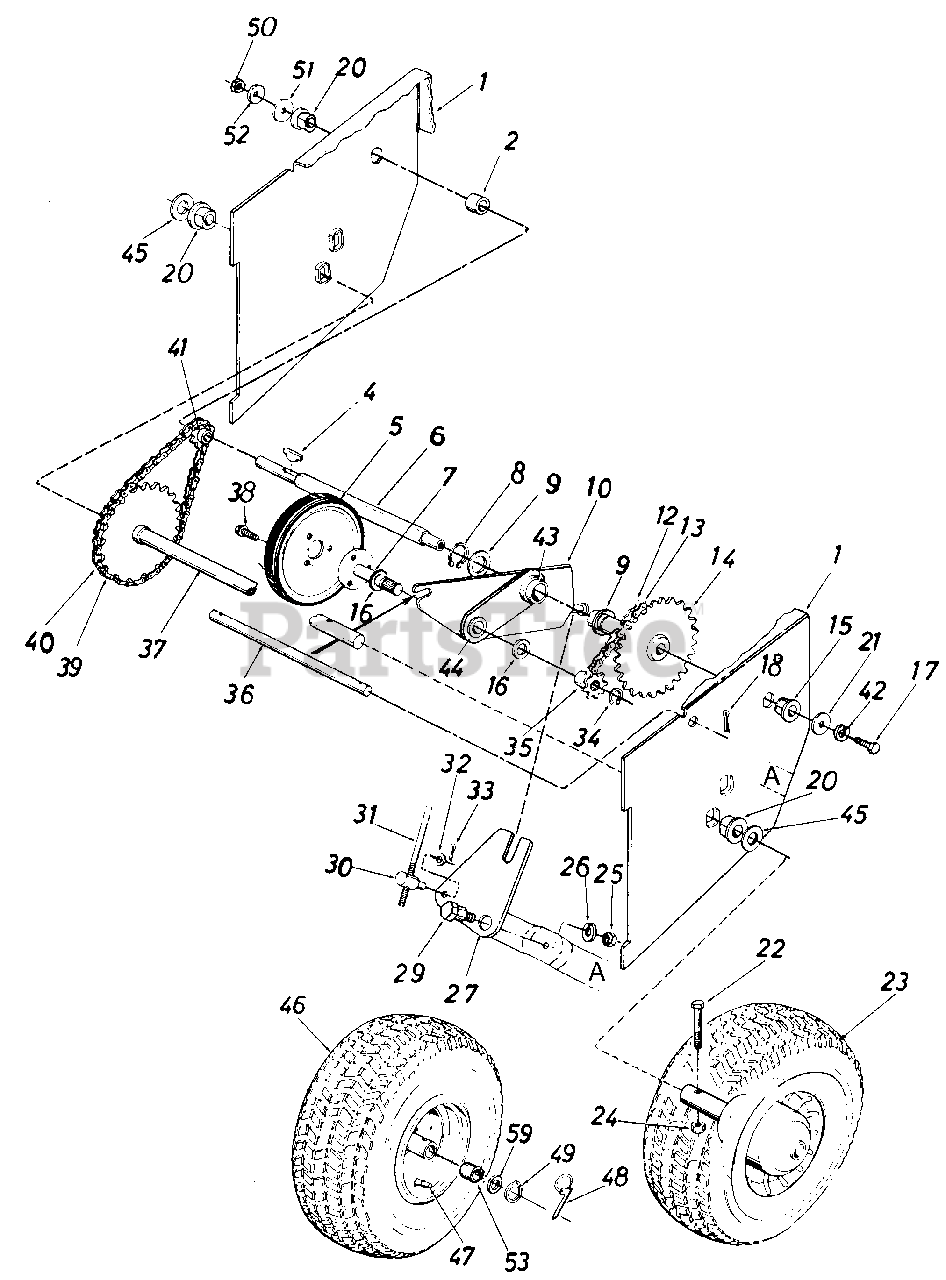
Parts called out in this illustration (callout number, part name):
1	FRAME ASSY
4	KEY-HI-PRO #4-3/32X5/8 DIA-HDN
5	WHEEL ASSY-FRICTION
6	SHAFT-HEX
7	PLATE ASSY-FRICTION WHEEL MTG
8	RING-SNAP FOR 1.00 DIA SHAFT
9	WASHER-FL-1.03 ID X 1.62 X .03 HD
10	BRACKET ASSY-SLIDING
12	#41 CHAIN 1/2" PITCH X 35 LINKS
13	#41 MASTER LINK 1/2 PITCH TYPEII
14	SPROCKET ASSY-32T
15	BEARING-FLANGE
16	WASHER-FL
17	SCREW-HEX 5/16-18 X .62
18	PIN-COTTER-3/32 DIA X .75
20	BEARING-FLANGE W/FLATS
21	WASHER-FL-.312 X 1.125 X .125
22	SCREW-5/16-24 X 1.5
24	NUT-HEX INS JAM LOCK 5/16-24
25	NUT-HEX JAM 3/8-18
26	WASHER-LOCK-3/8
27	BRACKET-LINKAGE
29	SCREW-SHLD .625 DIA X .163
30	FERRULE-ADJ
31	ROD-SHIFT
32	WASHER-FL-.344 X .62
33	PIN-COTTER-3/32 DIA X .75
34	RING-C SNAP
35	SPROCKET-7T
37	SPROCKET ASSY-28T
38	SCREW-HEX WASH SF TAPP
39	CHAIN 1/2" PITCH X 43 LINK
40	#41 MASTER LINK 1/2 PITCH TYPEII
41	SPROCKET-CENTER #41-8T
42	WASHER-LOCK-5/16
43	BEARING
44	BEARING-FLANGE .630 ID
45	WASHER-FL-.760ID X 1.49OD X .06HDN
47	VALVE-TUBELESS AIR
48	PIN-CLICK-5/16 DIA X 1.75LG
49	RING-SNAP FOR .750 DIA SHAFT
50	NUT-HEX INS L-1/2-20
51	WASHER-FL-.546 X 1.28 X .090
52	WASHER-BELL .505 ID X 1.00 OD
53	BEARING-SLEEVE
59	WASHER-FL .794ID X 1.240 X .060
